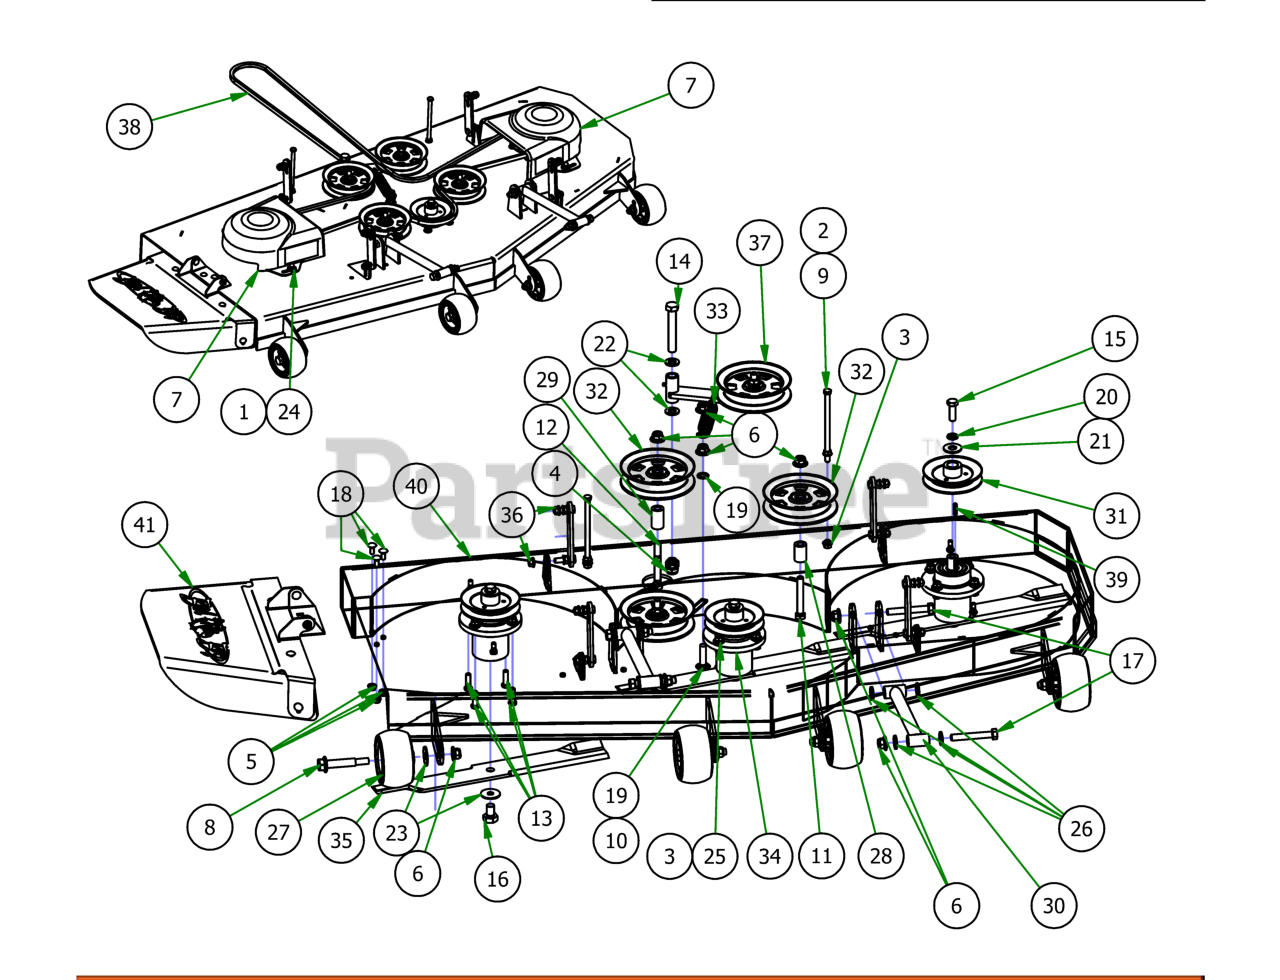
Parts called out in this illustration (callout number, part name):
1	Acorn nut-pulley Cover
2	3/8" Flange Nut
3	3/8-16 NYLON INSERT FLANGE LOCKNUT (GR.F) ZINC
4	5/8-11 Nylon Insert Jam Half Nut
5	5/16-18 NYLON INSERT FLANGE LOCKNUT ZINC
6	1/2-13 NYLON INSERT FLANGE LOCKNUT ZINC
7	Pulley Cover
8	Deck Wheel Bolt
9	3/8-16 X 6.5 HEX CAP SCREW (GR.5) ZINC
10	1/2 x 2" Carriage Bolt
11	1/2 x 3 1/2 Flange Bolt Grade 8
12	1/2" x 4" Bolt (Grade 8)
13	3/8" x 1 1/4" Hex Bolt
14	5/8" x 4" Hex Bolt
15	1/2"-20 x 1 1/2 - Grade 5 Fine Thread Bolt
16	5/8" x 1 1/2" Grade 8 Hex Bolt (Fine)
17	1/2-13 x 3 1/2 GR 5 Hex Bolt
18	5/16-18 x 3/4 Carriage Bolt
19	.517 Square Hole Round Washer
20	1/2" Lock Washer
21	5/8'' Flat Washer
22	.630 ID Plastic Washer
23	1/2" Belleville Washer
24	.360 ID Plastic Washer-Black
25	5/16 USS FLAT WASHER (7/8 OD) ZINC
26	.505 Nylon Spacer
27	Deck Wheel
28	.502 ID X .750 OD X 1.500 Long Spacer
29	1 3/4" Pulley Spacer
30	MZ/ZT Deck Locator
31	60" Avenger Deck Pulley
32	5-3/4 Idler Pulley
33	Deck Idler Spring
34	Spindle Assembly-MZ
35	60 Inch Fusion Blade
36	Deck Hanger Assembly
37	2017 54"/48" Deck Idler Assembly
39	3/16 X 1 SQ MACHINERY KEY 1018 STL ZINC
40	60" MZ Deck Welment-Painted
41	MZ Discharge Chute Assembly
